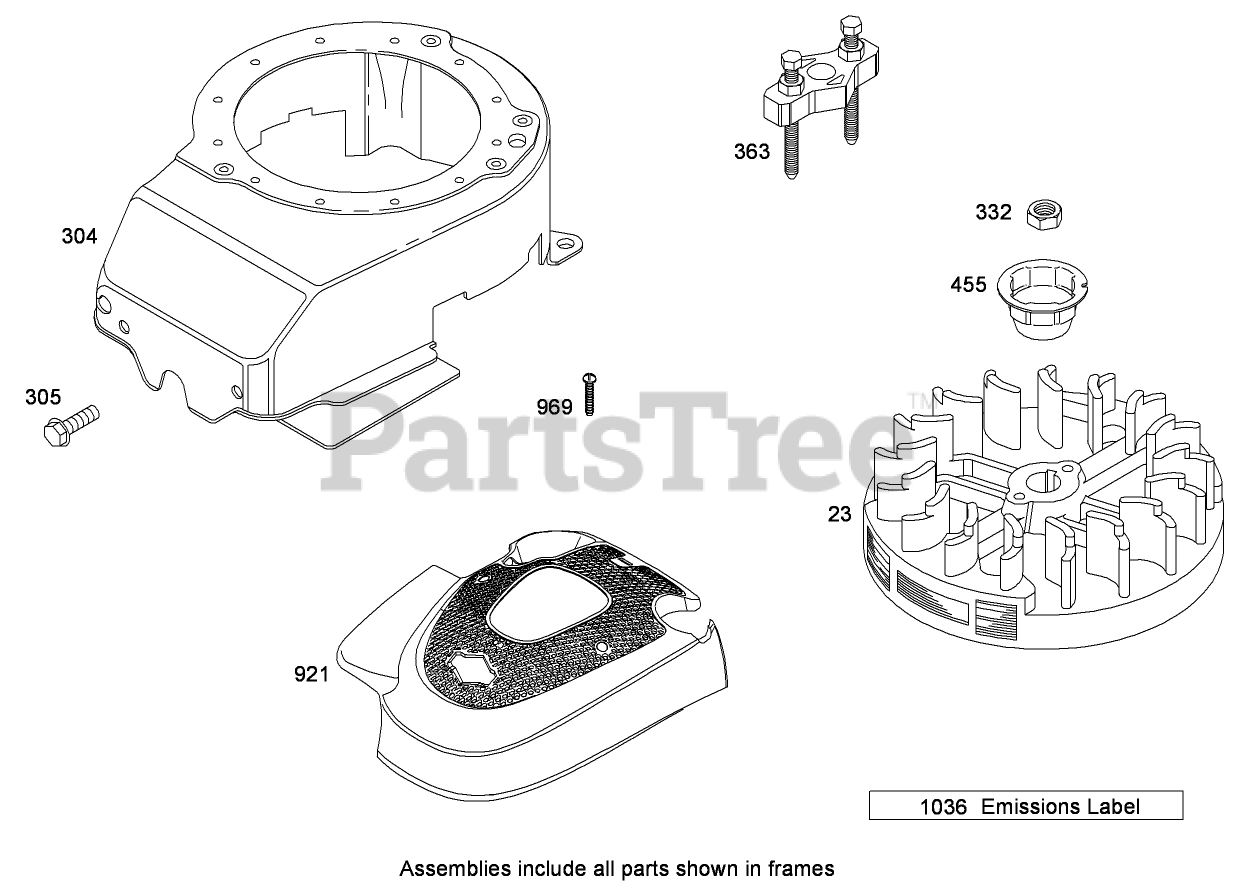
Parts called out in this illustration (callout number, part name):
23	Flywheel
304	Housing-Blower
305	Screw (Flywheel Guard)
332	Nut (Flywheel)
363	Puller-Flywheel
455	Gasket-Passage, Breather
921	Cover-Housing, Blower
969	Screw (Blower Housing Cover)
